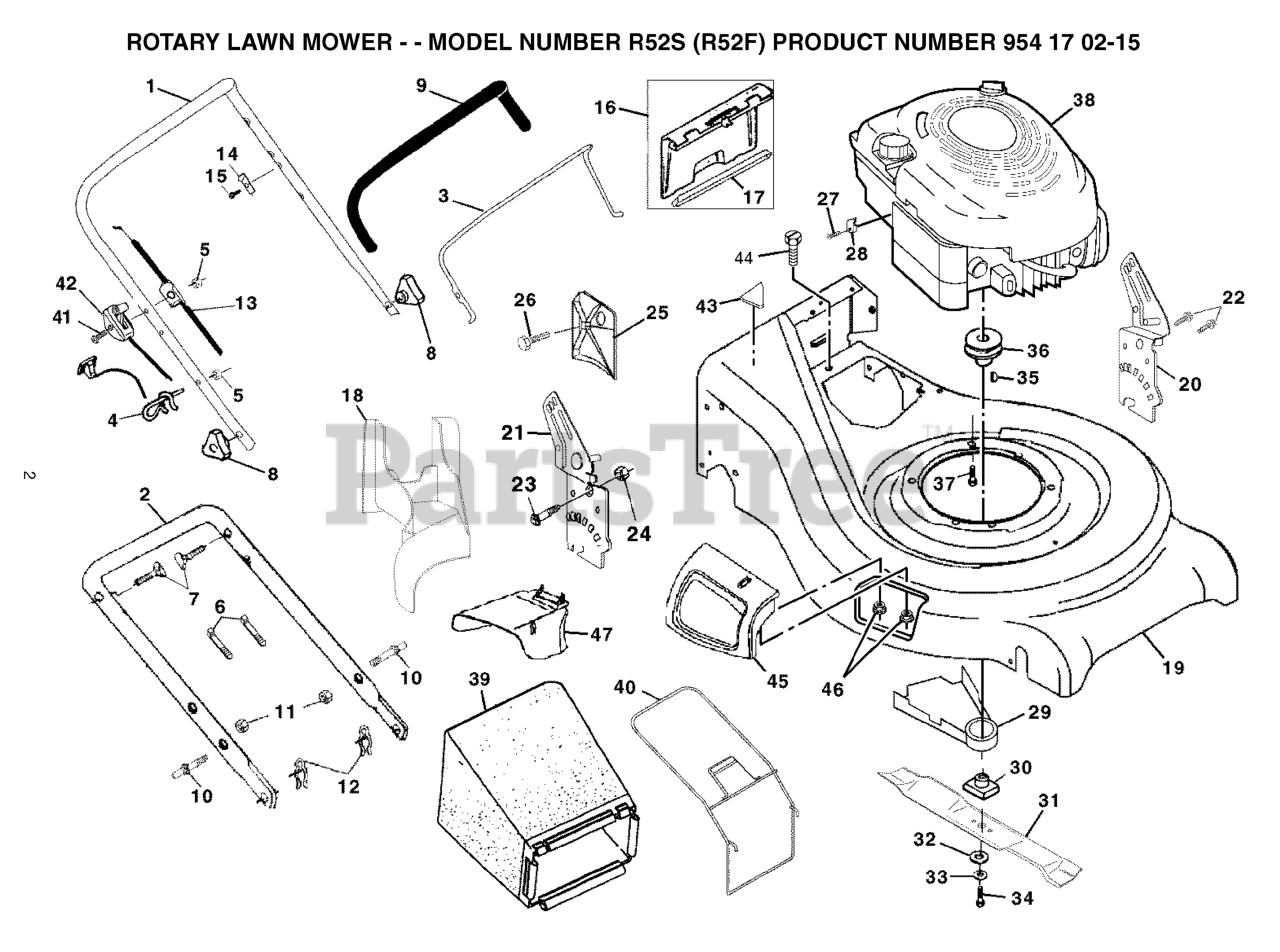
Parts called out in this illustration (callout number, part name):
1	HANDLE.UP.DLX.COMF.W/GRIP.GREY
2	HANDLE, LOWER
3	CONTROL BAR
4	ROPE, GUIDE
5	NUT
6	TIE GUIDE
7	HANDLE BOLT
9	GRIP.HANDLE.FOAM
10	BOLT
11	NUT
12	HAIRPIN COTTER
13	ENGINE ZONE CONTROL
14	BRACKET UPSTOP
16	KIT.DOOR.REAR.21.WRAPPED.BLACK
17	SEAL.DOOR.21" (2 2MC)
18	PLUG, MULCHER
20	.RACKET
21	RIGHT HANDLE BRKT. ASSM.
22	SELF-TAPPING SCREW 5/16-18X3/4
23	BOLT, HEX HEAD 5/16-18
24	NUT.71038.31-18.HEX.NYLOCK
25	CLIPPING DEFLECTOR
27	SCREW.HEX.HEAD.WASHER.10-16
28	CABLE CLAMP(ENGINE)
30	BLADE ADAPTER
32	WASHER,HARDEN
33	LOCKWASHER
34	SCREW, HEX HD 3/8-24 X 1-3/8
35	HI-PRO KEY
36	PULLEY.ENG.25MMM
37	BOLT 3/8-16X1-1/8
40	FRAME.GRASS.CATCHER.21.RGD
42	CONTRL.THROTTLE.
43	DECAL.INTERNATIONL.CUTFINGER
45	MULCHER DOOR ASM.
47	DEFLECTOR, DISCHARGE
